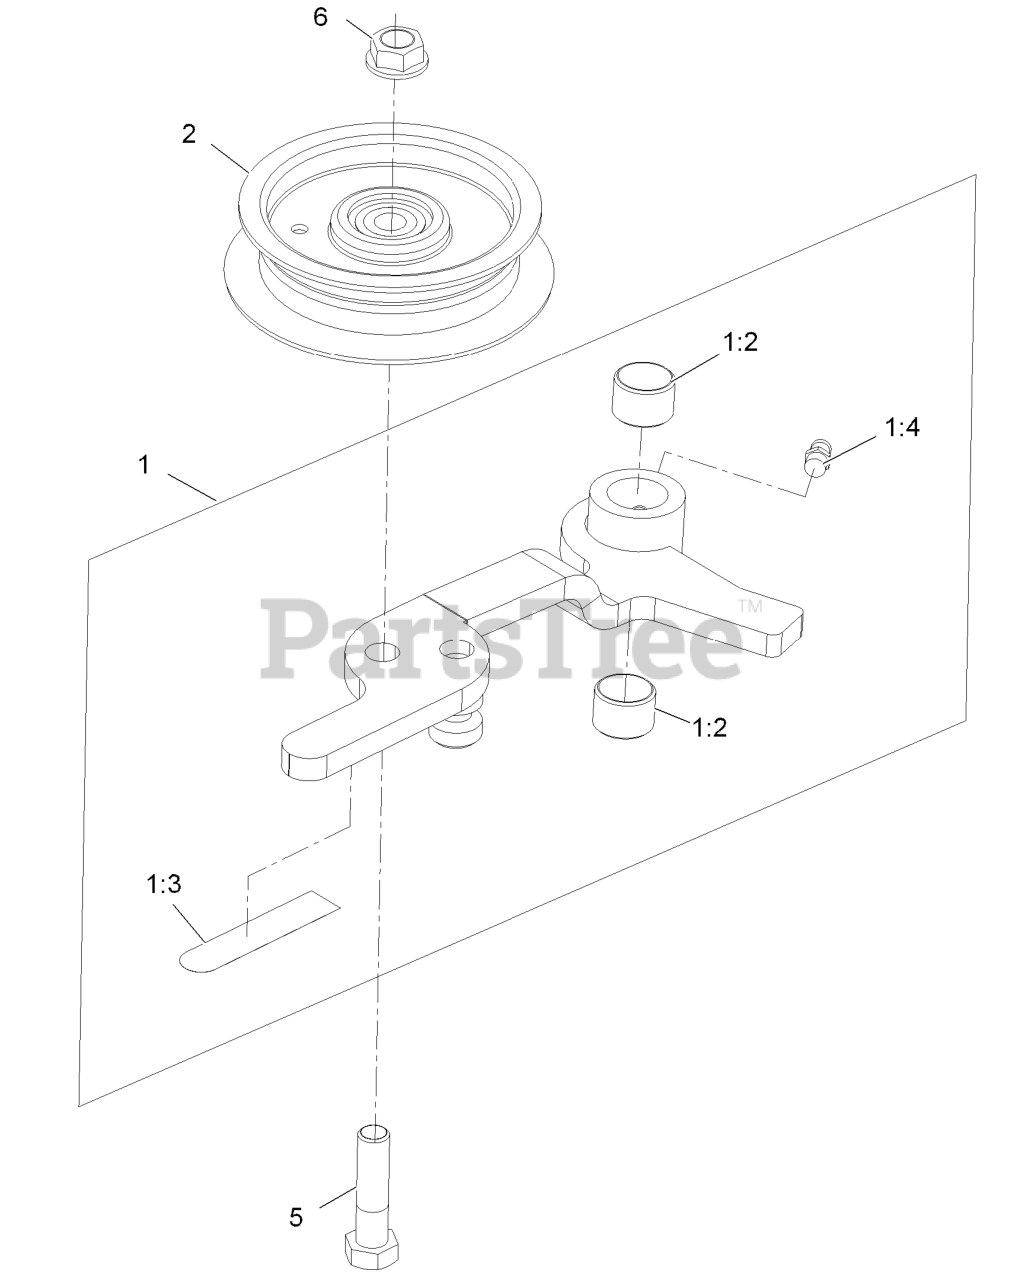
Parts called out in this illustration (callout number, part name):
1	Idler Assy With Bushings, Zerk, And Decal
1:2	Bearing
1:3	Decal-Warning
1:4	Zerk-1/4-28 Str
2	Idler-Flat
5	Screw-HH 3/8-16 X 1 1/2
6	Nut-Whizlock 3/8-16
